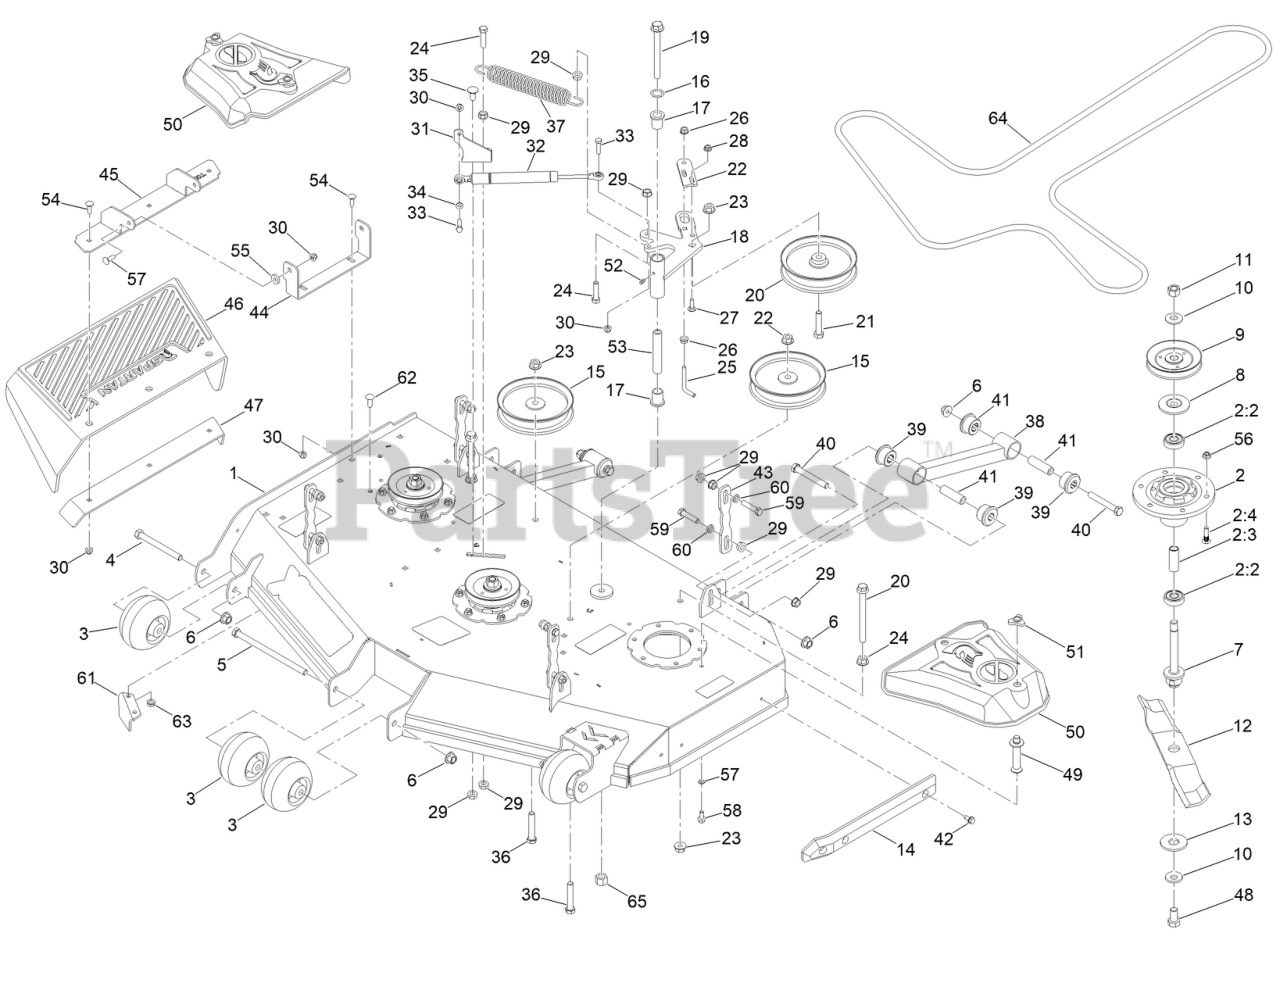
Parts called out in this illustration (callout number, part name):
1	ASM- 48" DECK W/DECALS
2	SPINDLE ASM 5IN DECK
2:2	BEARING
2:3	SPACER, BEARING
2:4	BOLT-ROUND HEAD
3	MWR ANTI-SCALP WHL W/O GREASE FITTING
4	SCREW-HH
5	1/2-13 X 8-1/2 HEX C/S GR 2 ZINC YELLOW
6	NUT-LOCK
7	SHAFT - SPINDLE
8	GUARD-BEARING TOP 0.673IN
9	PULLEY
10	M16 SPRING WASHER (39MMOD/ 3.9MM THK)
11	M16X1.5 C8.8 HEX NUT
12	BLADE-ROTARY
13	WASHER-HEX
14	MWR NYLON DECK GUARD
15	6-3/4IN IDLER PULLEY 15/16IN SPACER ASSY
16	.767IDX1.125ODX.016 THK TRIP WV WASHER
17	3/4IN ID X15/16IN OD X 1-1/8IN FLNG BUSH
18	MWR DECK IDLER PULLEY ARM ASSY PAINT
19	1/2-13 X 5-1/2 HEX FLANGE BOLT GR 8 ZY
20	6-3/4IN IDLER PULLEY 7/16IN SPACER ASM
21	SCREW-HH
22	DECK IDLER PULLEY BELT RETNR BRKT PAINT
23	NUT-HHF
24	SCREW-HH
25	BOLT-L
26	3/8-16 HEX FLANGE NUT W/SERR ZINC YELLOW
27	BOLT-CARR
29	NUT-HF
30	NUT-HF, NI
31	BRACKET- IDLER DAMPER
32	IDLER GAS SPRING
33	SCREW-HH
34	.312IDX.625ODX.062 THK THRUST BRG OI BRZ
35	SCREW-CARR
36	1/2-13 X 2-3/4 HEX FLANGE BOLT (GR.8) YZ
37	MWR DECK SPRING
38	RZ MWR DECK STABLZR ASSY
39	RED A80 SUSP BUSHING
40	1/2-13 X 3-3/4 HEX C/S (GR.5) ZC/YEL
41	UTV A-ARM BUSHING SLEEVE
42	SCREW-HWH, THREAD CUT
43	HANGER-DECK PAINTED GREY
44	BRACKET-CHUTE
45	DECK CHUTE HINGE ASM
46	RZ MWR RUBBER DISCHARGE CHUTE
47	MWR DECK CHUTE HINGE BACKER BRKT
48	M16X1.5-30MM C10.9 HEX BOLT
49	PIN-BELT COVER
50	COVER BELT
51	NUT-KNOB
52	1/4IN DRIVE TYPE GREASE FITTING YZ
53	MWR INNER IDLER SPACER
54	5/16-18 X 1 CARRIAGE BOLT GR 8 YZ
55	.312 ID X .875OD X .1875 THK F/W NYL
57	WASHER-LOCK
58	SCREW-HHF
59	SCREW-HH
60	.443 ID X .749 OD X .125 THK NYLON BLACK
61	BAFFLE-DISCHARGE
62	SCREW-CARR
63	NUT-HF, NI
64	BELT-V
65	NUT-LOCK, NI
